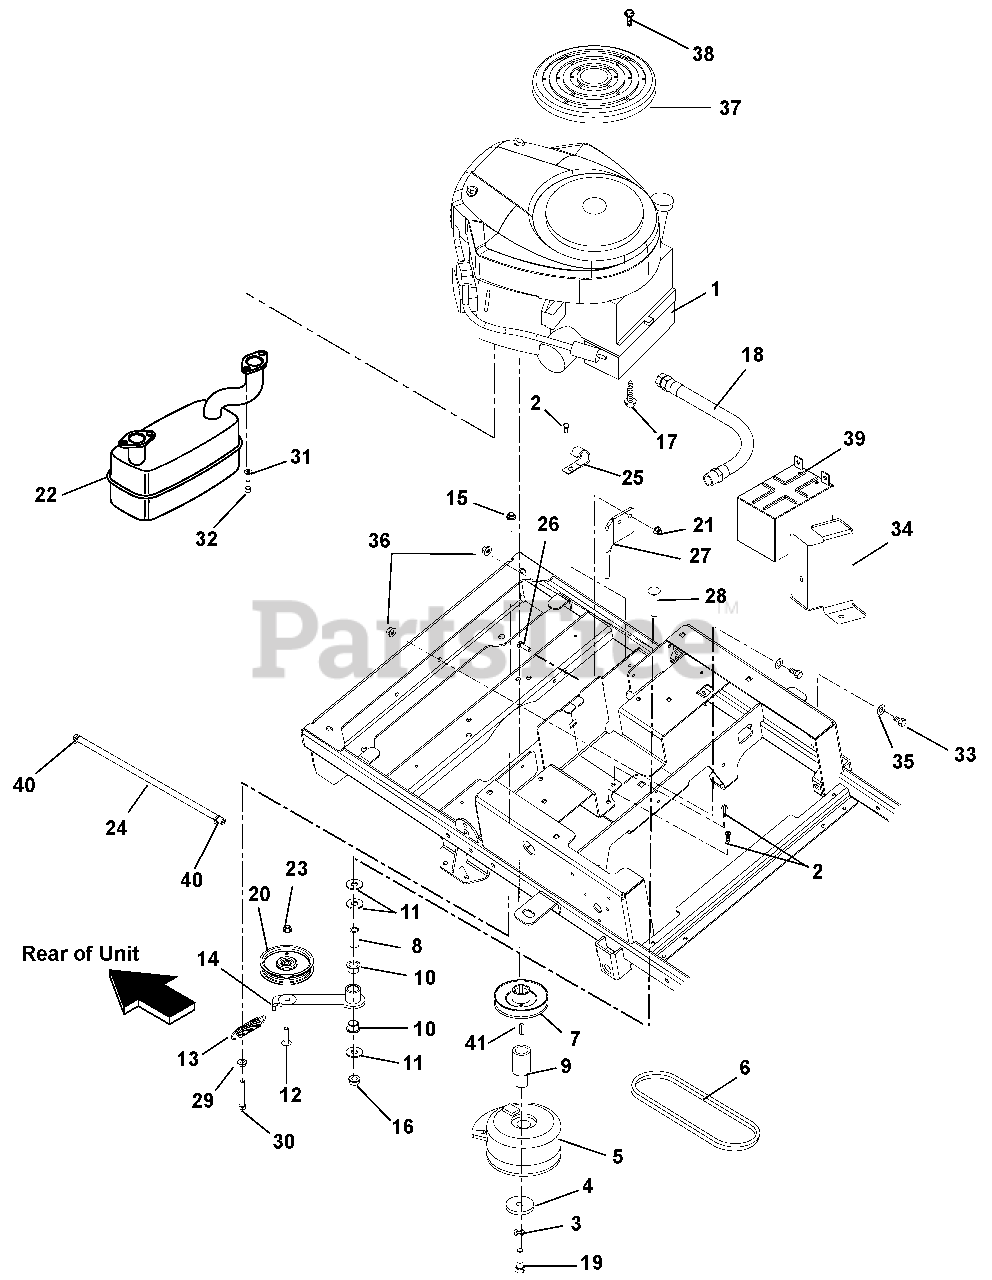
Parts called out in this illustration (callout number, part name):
1	Engine, 18HP V-Twin CE
2	Screw, Tapping .250-20 x .37 Hex Washer Head
3	Washer, Locking .44 x .109 Regular
4	Washer, Flat Steel .469 x 2.00 x .25
5	Clutch, XL
6	Belt, HA 62.50 Wrapped
7	Pulley, V 4.5 x 1.5 AB Section with Key
8	Bushing, Sleave .500 x .750 x .1.560
9	External, Crankshaft Lower
10	Bushing, Flange 0.75 x 0.875 x .625 x 1.125
11	Washer, Flat Steel .563 x 1.38 x .109
12	Bolt, Round Head Square Neck .38-16 x 1.50 Grade 5
13	Spring, Tension .105 x .812 x 3.88
14	Weldment, Ground Drive Idler Arm
15	Nut, 3/8-16 Flange Nyloc
16	Nut, Locking Top Flange .50-13
17	Screw, Tapping .38-16 x 1.00 Hex Washer Head
18	Hose Assembly, Oil Drive .38 x 11.5 OAL
19	Bolt, Hex .44-20 x 4.50 Grade 8
20	Assembly, 4" Idler
21	Nut, .31-18 Nyloc Flange
22	Muffler, Briggs & Stratton Twin
23	Nut, Locking Top Flange .38-16
24	Fuel Hose
26	Bolt, Hex .31-18 x 1.00 Grade 5
27	Clutch Stop
28	Bolt, Round Head Square Neck .50-13 x 2.50 Grade 5
29	Nut, Flange .375-16
30	Bolt, Hex .38-16 x 2.50 Grade 5
31	Washer, Locking .31 x .078 Regular
32	Screw, Cap .31-18 x .75
33	Bolt, Hex .25-20 x .75
34	Bracket, Battery Hold Down
35	Washer, Flat Steel .281 x .62 x .065
36	Nut, KEPS .250-20
37	Guard, Briggs & Stratton Engine
38	Screw, 8-16 x .87
39	Battery, 12V, 215 CCA, GEP
40	Clamp, Fuel Line
41	Key, Straight .25 x 2.0 x .25
